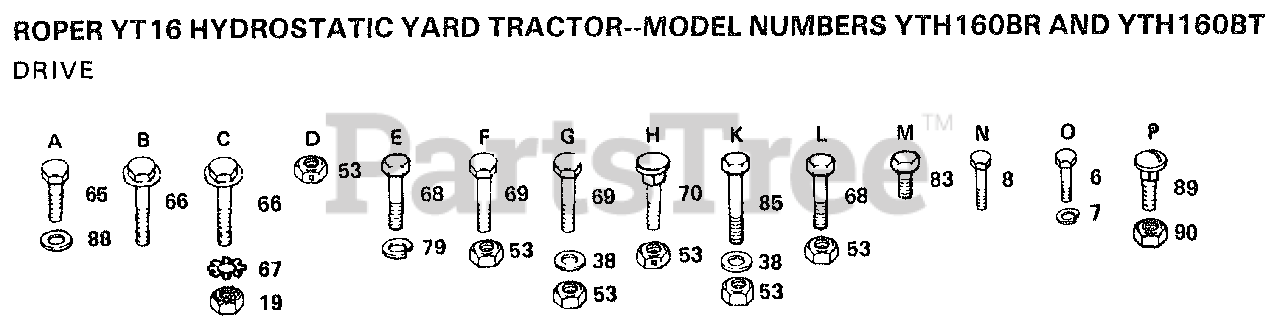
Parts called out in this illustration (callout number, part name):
6	BOLT
7	LOCKWASHER
19	NUT
38	WASHER
65	SCREW
66	SCREW LT
67	LOCKWASHER
69	BOLT
70	BOLT
79	LOCKWASHER
83	SCREW
85	BOLT
88	WASHER
89	BOLT
